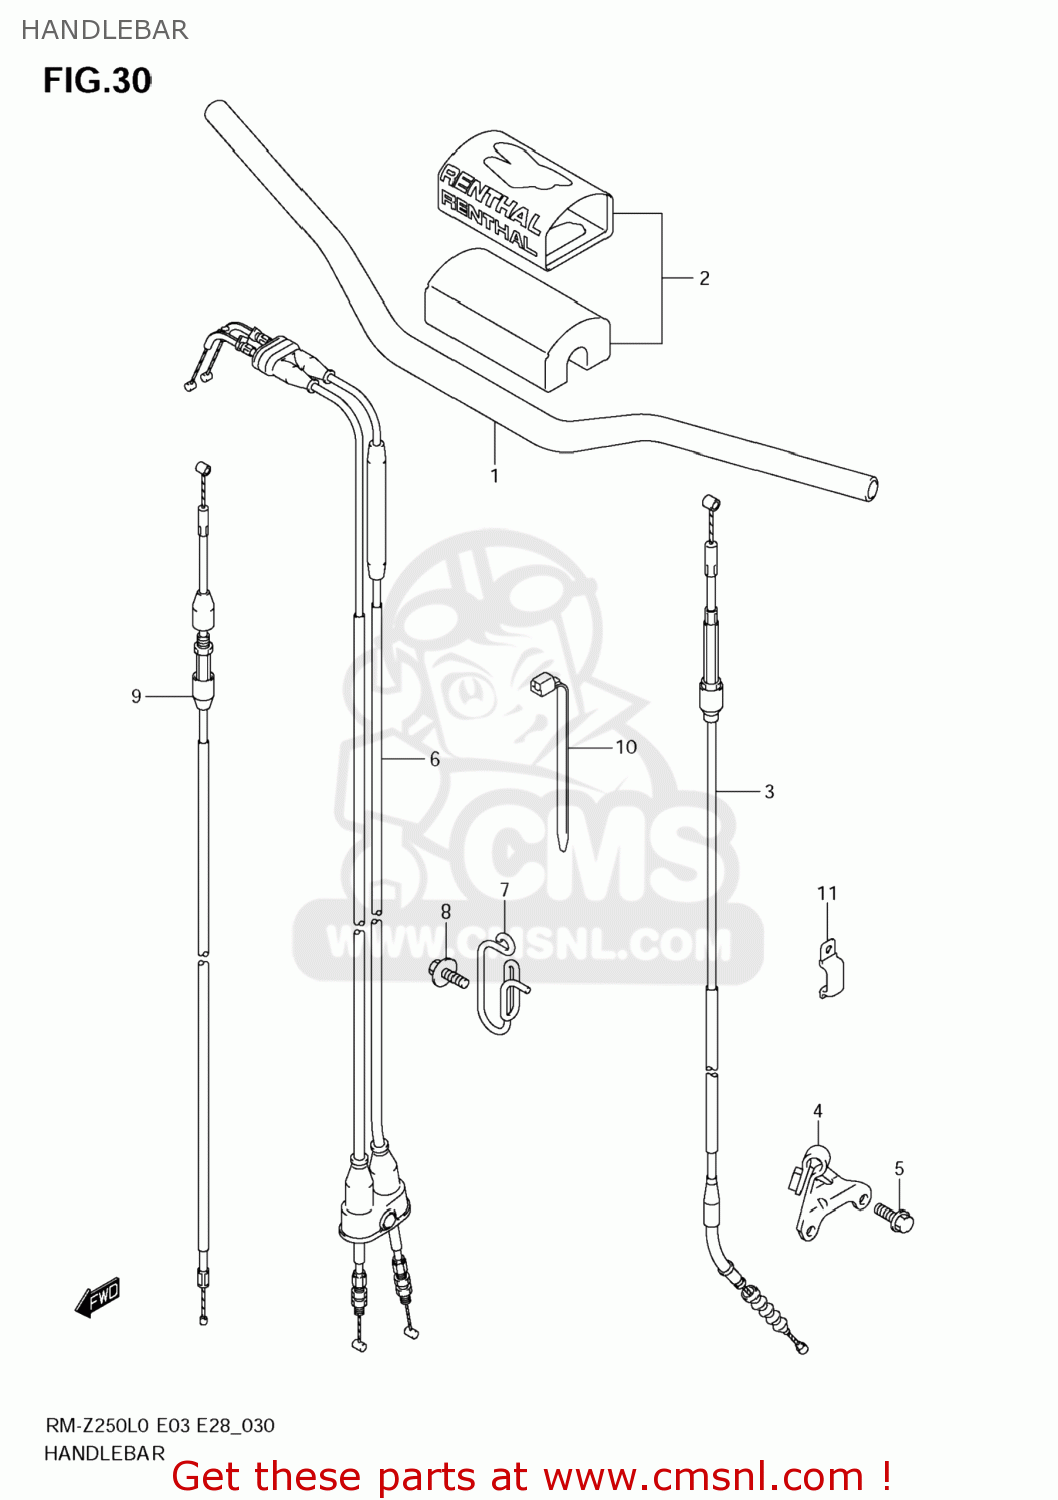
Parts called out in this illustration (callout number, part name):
1	HANDLEBAR
2	PAD SET,HANDLEBAR (NAS)
3	CABLE ASSY,CLUTCH
4	BRACKET,CLUTCH CABLE
5	BOLT(6X12)
6	CABLE SET,THROTTLE
7	GUIDE,THROTTLE & STARTER CABLE
8	BOLT(6X16)
9	CABLE ASSY,HOT STARTER
10	CLAMP(L:125)
11	CLAMP
